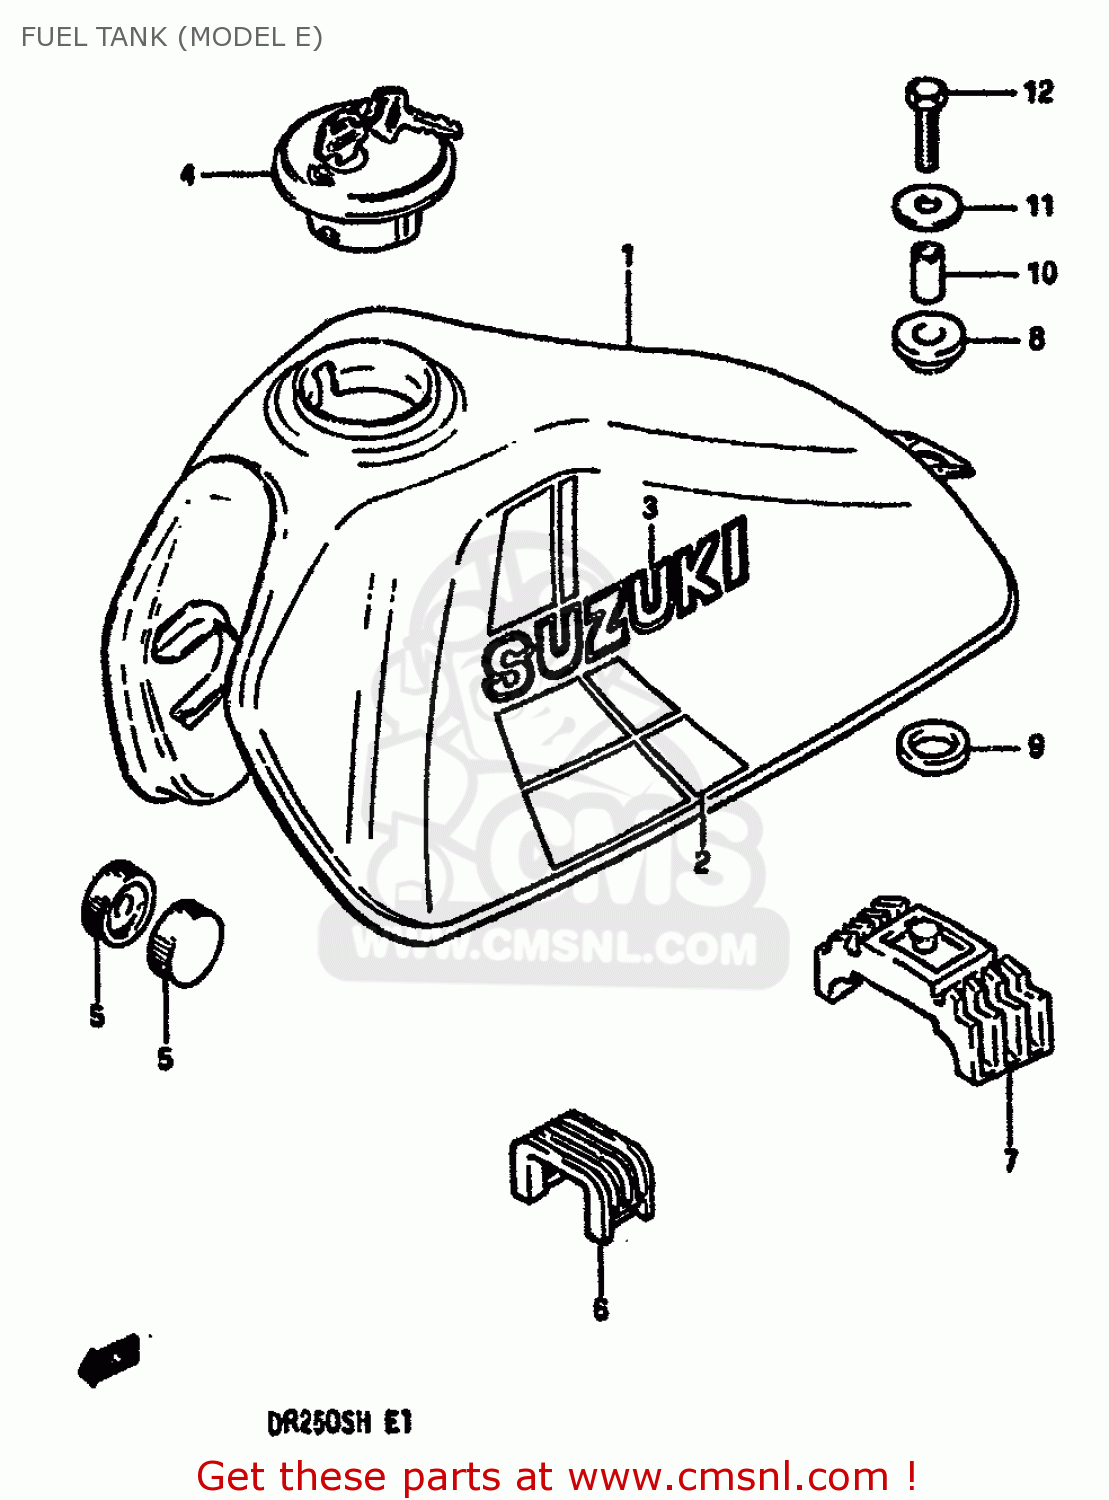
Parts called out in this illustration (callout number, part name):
1	TANK ASSY,FUEL (RED)
2	TAPE SET,FUEL TANK
3	EMBLEM
4	CAP SET,FUEL TANK
5	CUSHION
6	CUSHION,TANK UPR FR
7	CUSHION,FUEL TANK,REAR
8	CUSHION
9	CUSHION
10	SPACER(8.5X12X19)
11	WASHER (8.5X29X1.6)
12	BOLT
